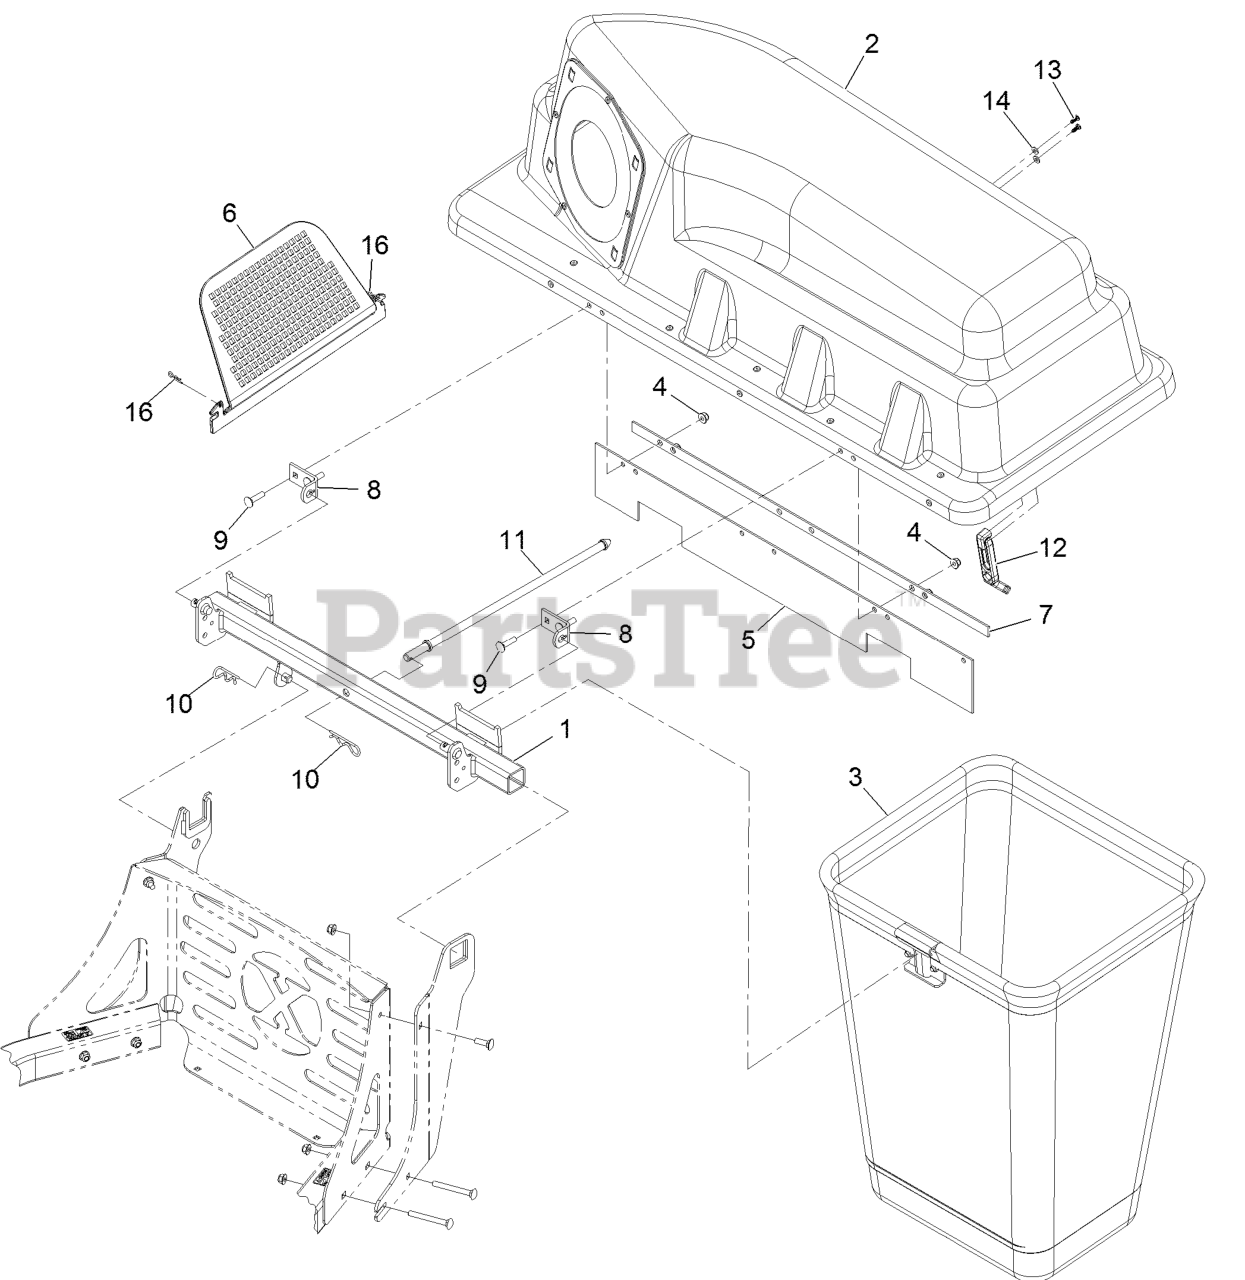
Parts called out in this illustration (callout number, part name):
1	FRAME PIVOT ASM
2	BAGGER HOOD ASM
3	BAG AND FRAME ASM
4	NUT-HF, NI
6	SCREEN-BAGGER
7	PLATE-BACKING
8	BRACKET-PIVOT, HOPPER
9	Bolt-Carriage 5/16-18 X 1 1/4
10	PIN-HAIR
11	ROD-HOLD DOWN, HOOD
12	LATCH-RUBBER
13	SCREW-PLASTITE
14	WASHER-FLAT
